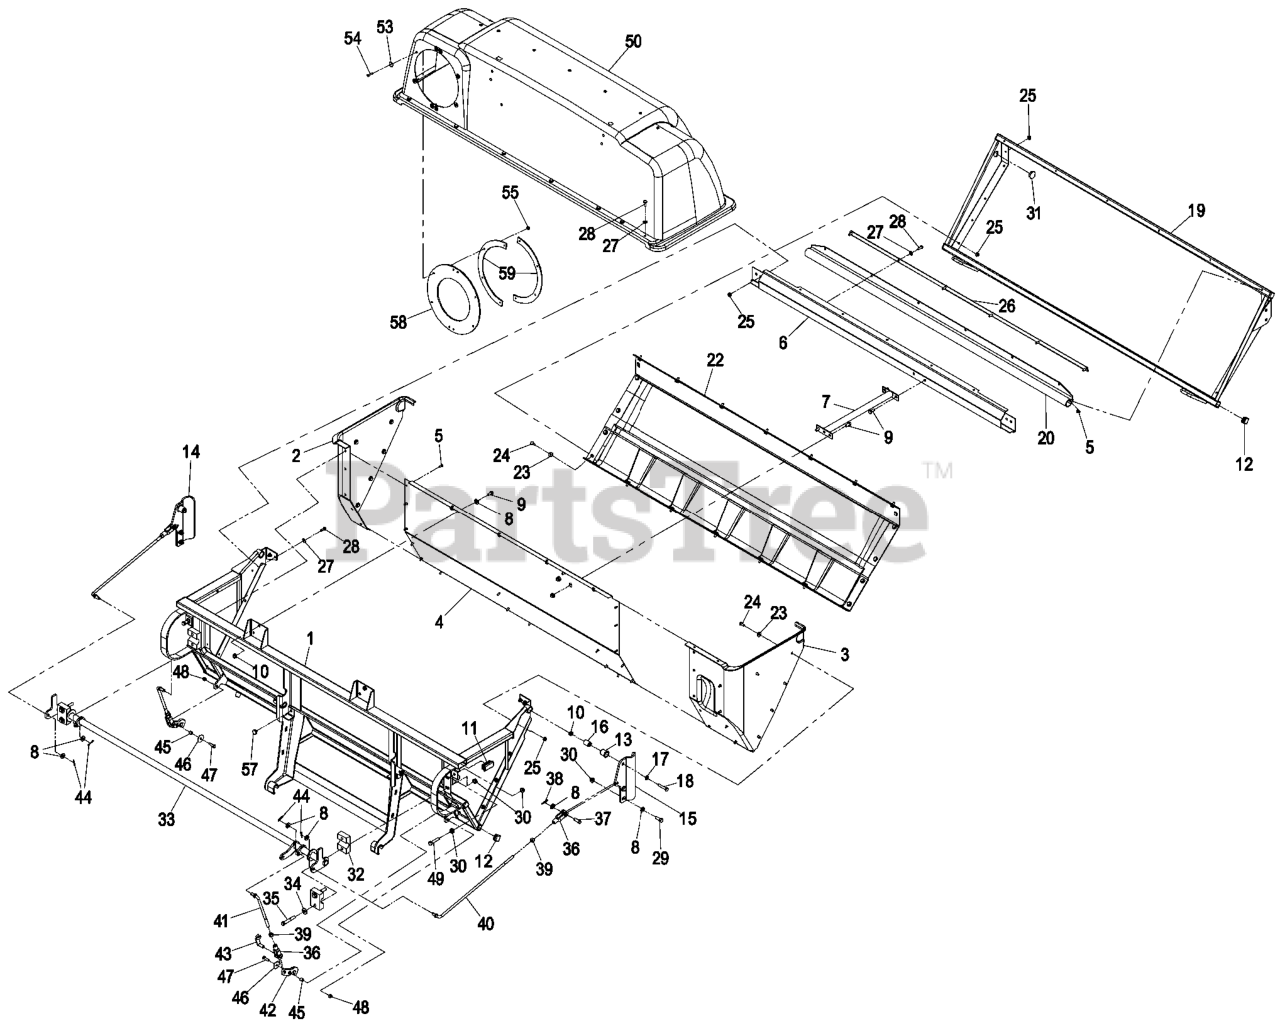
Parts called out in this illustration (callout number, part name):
2	PANEL-BAGGER, RH
3	PANEL-BAGGER, LH
4	SHEET-WALL
5	RIVET-BLIND
6	REAR CROSSMEMBER ASM
8	WASHER-FLAT
9	SCREW-HH
13	BUSHING
14	ARM-HINGE, RH
15	ARM-HINGE, LH
16	PIN-PIVOT, HINGE
17	WASHER-PLAIN
18	SCREW-HH
19	DOOR ASM
20	SEAL-DOOR HINGE
22	BAG AND BOTTOM PANEL ASM
23	WASHER-FLAT
24	SCREW-HH
26	STRAP-HOLD DOWN
27	WASHER-FLAT
28	SCREW-HH
29	SCREW-HH
30	NUT-HHF, WHIZ
31	PLUG-DOME
33	LINK-INTERMEDIATE
34	WASHER-FLAT
35	BOLT-CARR
36	YOKE-LINKAGE, BRAKE
37	PIN-CLEVIS
38	PIN-COTTER
39	NUT-HEX
40	LINK-HINGE
41	LINK-HANDLE
43	PIN-SPRING, CLEVIS
44	PIN-COTTER
46	WASHER-FLAT
47	SCREW-HH
48	NUT-LOCK, NI
49	SCREW-HH
50	ASM,HOOD DUMP
53	WASHER-FLAT
54	SCREW-PPH
55	NUT-LOCK, NI
58	SEAL-TUBE
59	CLAMP-SEAL
